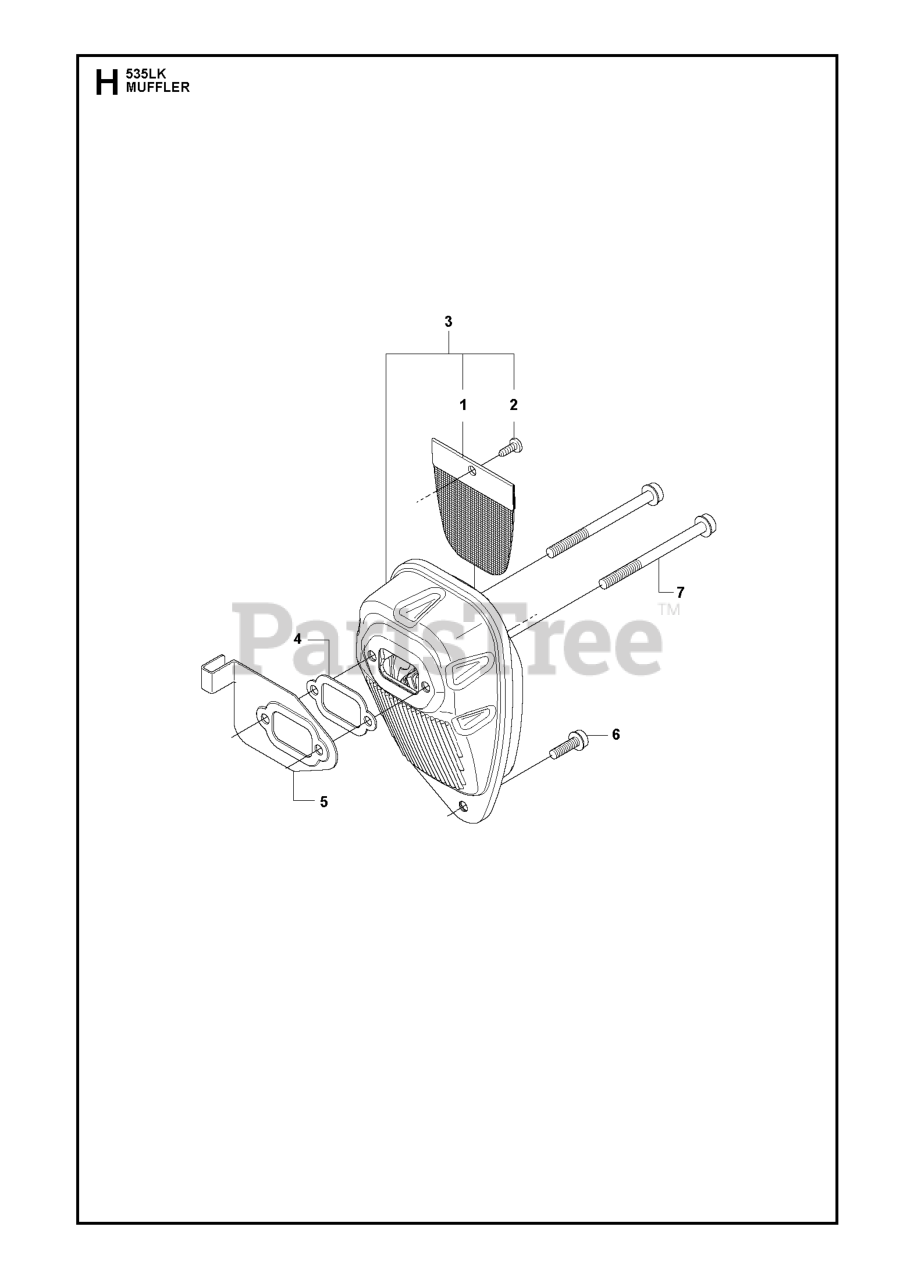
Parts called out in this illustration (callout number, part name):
1	SPARK ARRESTER SCREEN
3	MUFFLER
4	GASKET MUFFLER
